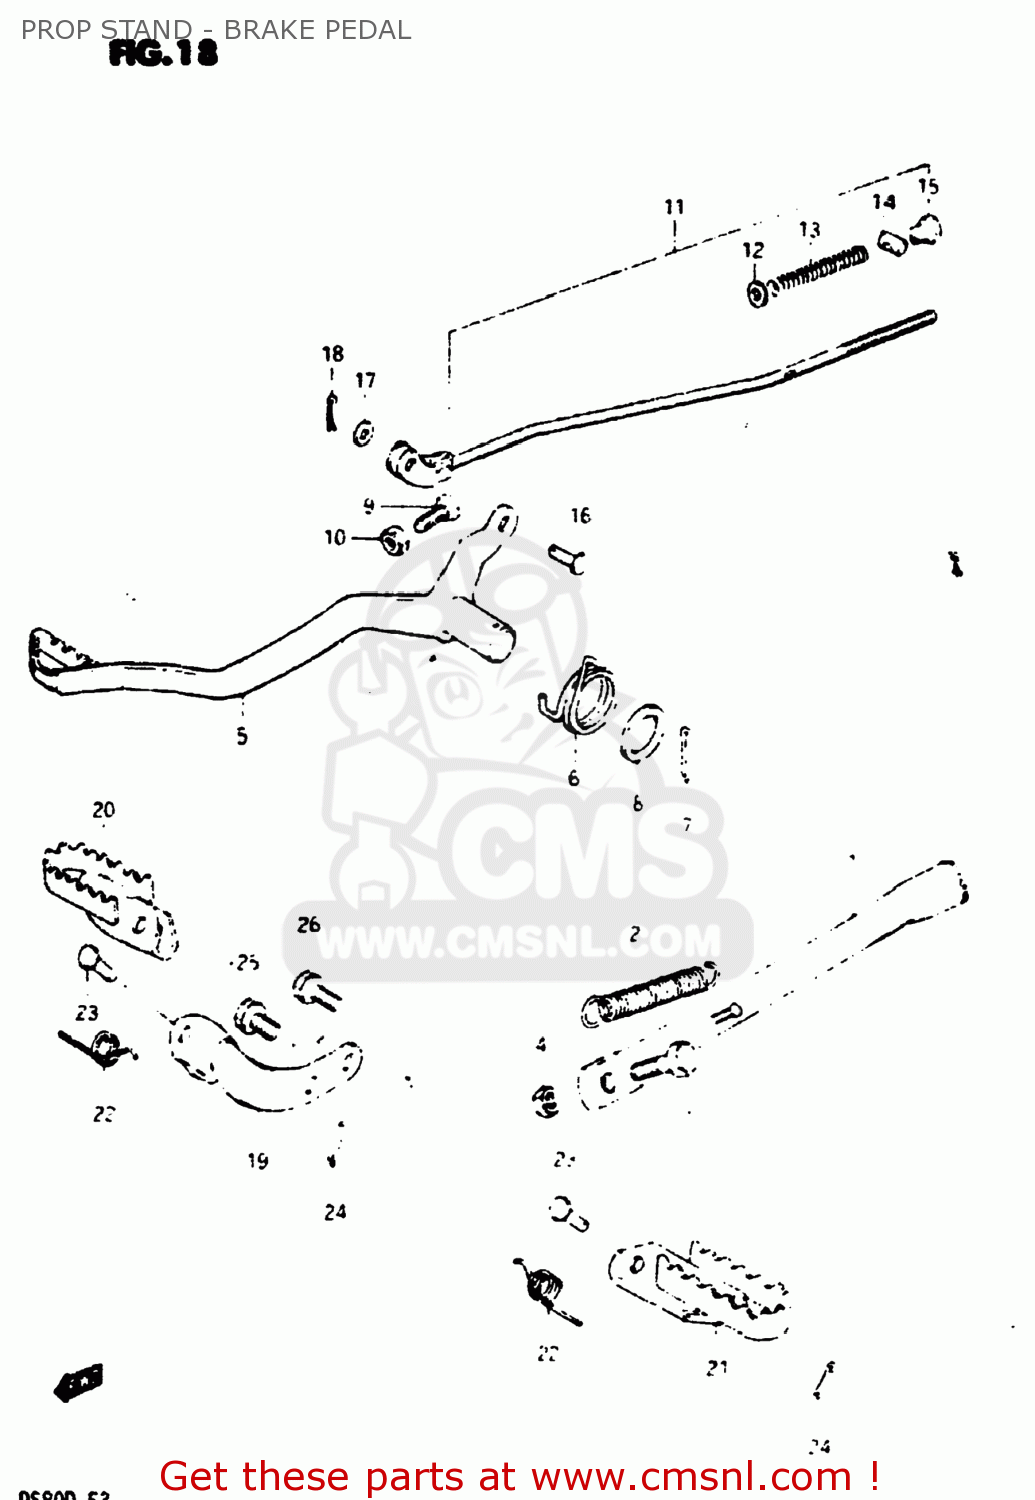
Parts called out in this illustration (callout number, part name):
1	STAND,SIDE
2	SPRING
3	BOLT
4	NUT
5	PEDAL,BRAKE
6	SPRING
7	COTTER PIN
8	WASHER(15.5X26X2.3)
9	BOLT(6X23)
10	NUT
11	ROD ASSY,RR BRAKE
12	WASHER
13	SPRING
14	PIN(11X18)
15	NUT (6MM)
16	PIN(L:13.5)
17	WASHER
18	PIN 20X20
19	BAR,FRONT FOOTREST
20	FOOTREST,FRONT,RIGHT
21	FOOTREST
22	SPRING
23	PIN
24	PIN 20X20
25	BOLT
26	BOLT
